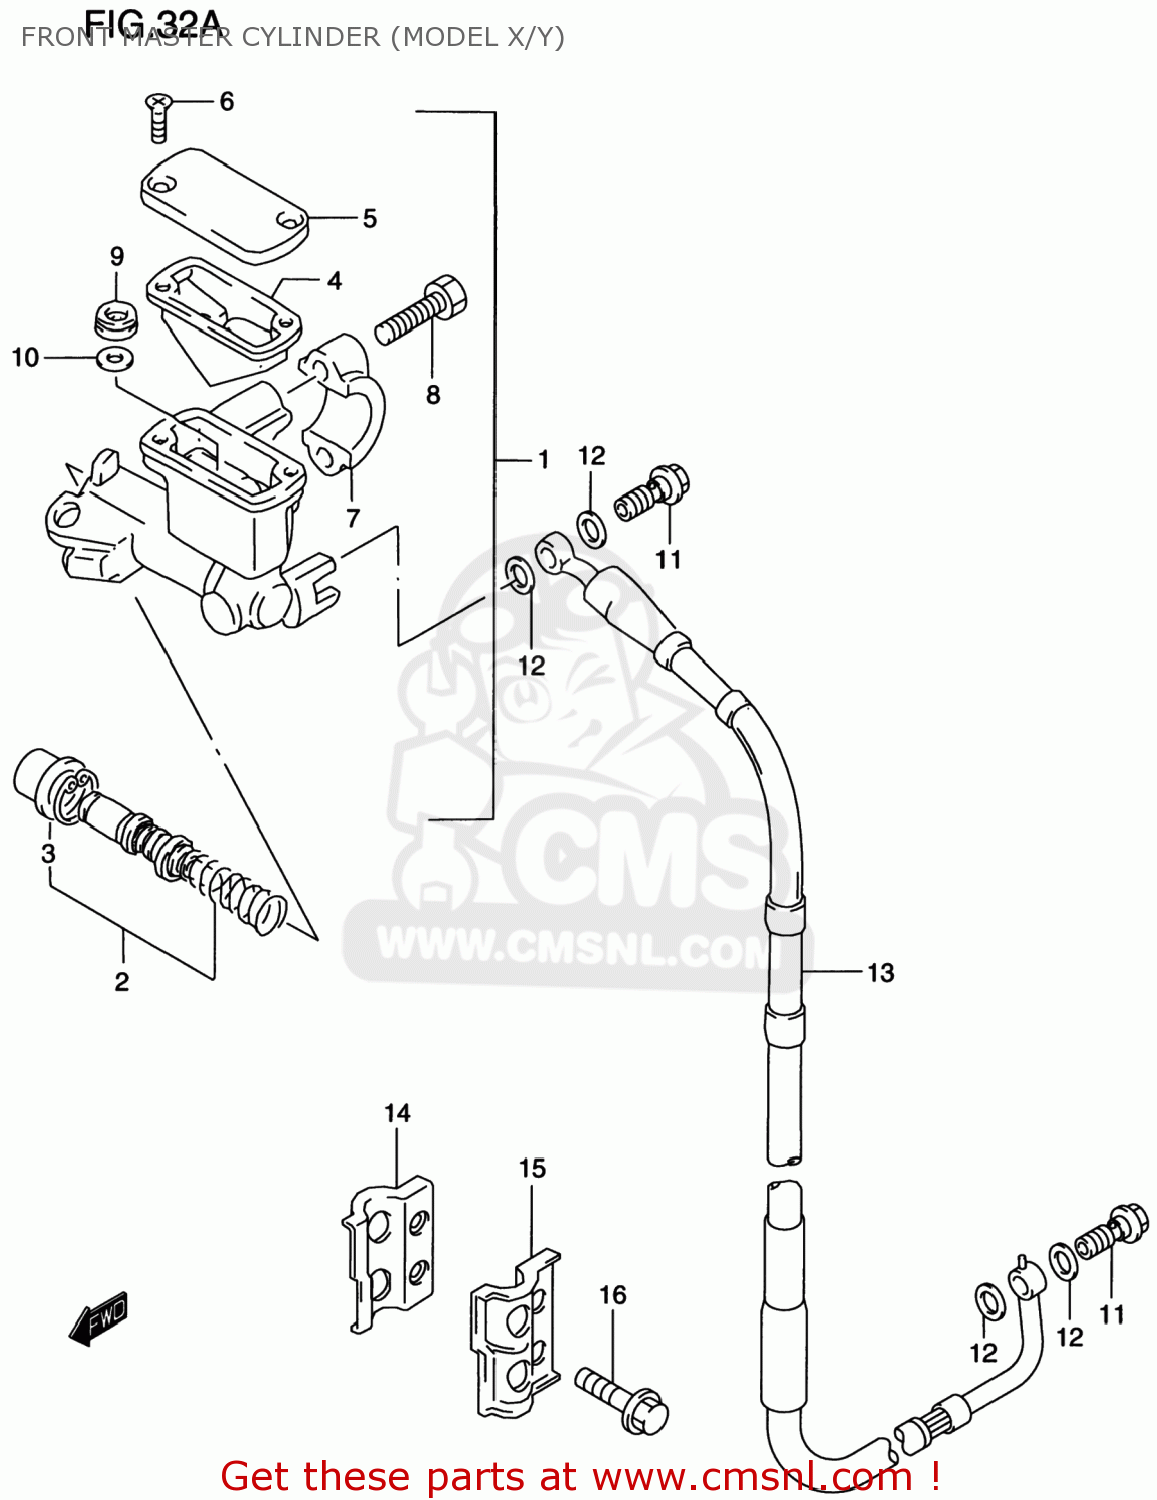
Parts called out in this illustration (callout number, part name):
1	CYLINDER ASSY,FR MASTER
2	PISTON & CUP SET
3	BOOT
4	DIAPHRAGM
5	CAP
6	SCREW
7	HOLDER
8	BOLT
9	SEPARATOR
10	RING
11	BOLT UNION
12	WASHER(10X15X1.5)
13	HOSE,FR BRAKE
14	CLAMP,FR BRAKE HOSE INNER
15	CLAMP,FR BRAKE HOSE OUTER
16	BOLT
